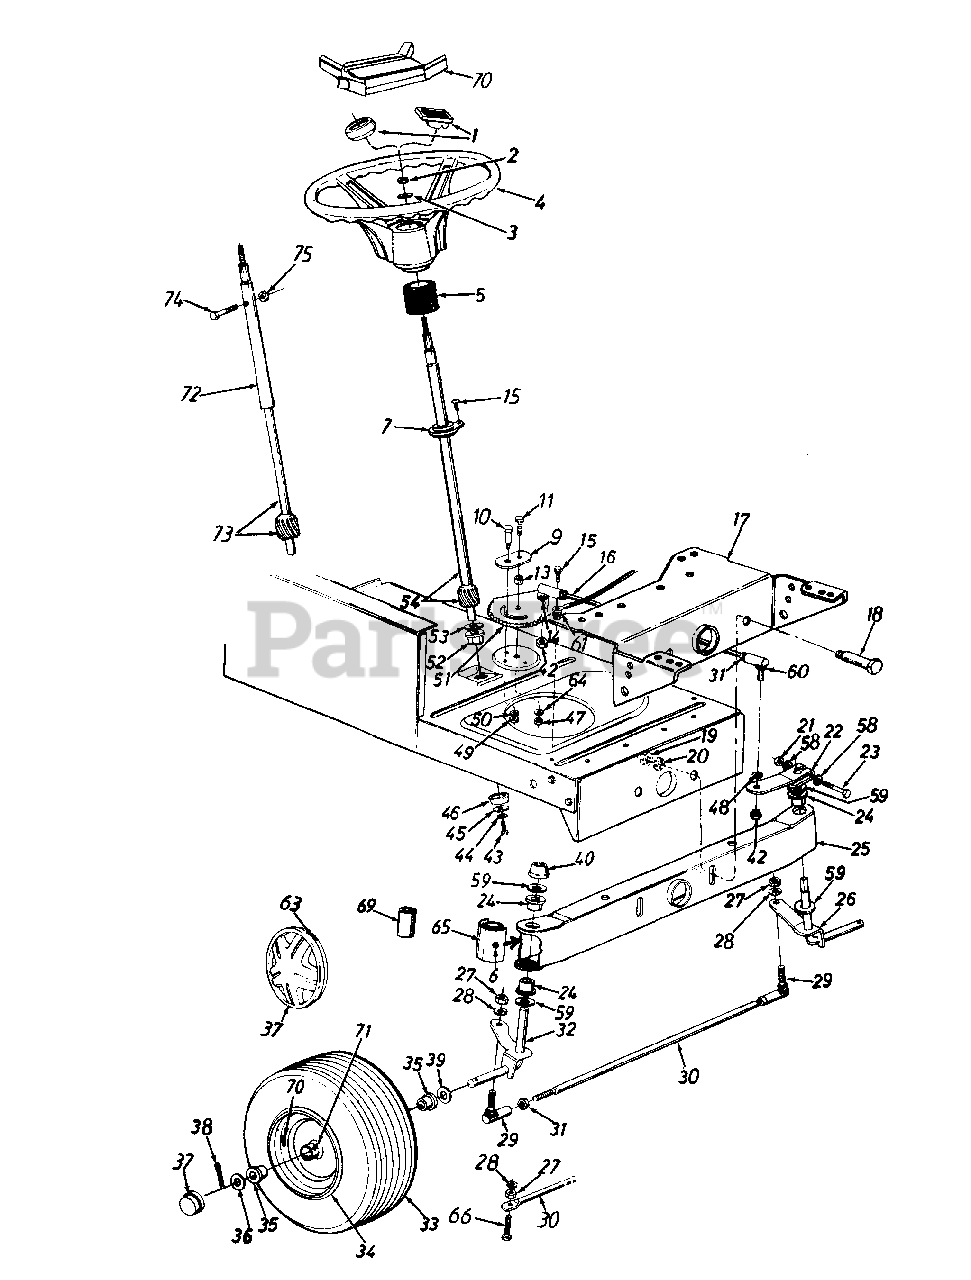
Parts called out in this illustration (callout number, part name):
1	Steering Wheel Cap
2	Hex L-Nut 5/16-24 Thd.
3	Belleville Wash. .345" I.D.
4	Steering Wheel (3 Spoke)
5	Steering Bellow - 4.5"
6	Grease Fitting
7	Flange Bearing .628" I.D. x 1.36 O.D.
9	Retainer Plate
10	Shoulder Bolt .437" Dia. x .35 Lg. 5/16-18 Thd.
11	Hex Bolt 3/8-24 x 1.0" Lg. (Gr. 5)
13	Spacer .380" I.D. x .625" O.D. x .227
14	L-Wash. 3/8" I.D. (H.D.)
15	Hex Wash. Hd. Self-Tap Scr.
16	Steering Drag Link
18	Shoulder Bolt .498" Dia. x 2.04 Lg. 3/8-16 Thd.
19	Flanged L- Nut 3/8-16 Thd.
20	L-Wash. 3/8" I.D.
21	Hex L-Nut 5/16-24 Thd.
22	Steering Arm Front Axle
23	Hex Bolt 5/16-24 x 2.00" Lg. (Gr.5)
24	Hex Flg. Brg. .632 I.D.
26	Front Axle Ass'y. - L.H.
27	Hex Nut 3/8-24 Thd.
28	L-Wash. 3/8" I.D.
29	Ball Joint 3/8-24 Thd.
30	Tie Rod (Adjustable)
31	Hex Jam Nut 3/8-24 Thd.
32	Front Axle Ass'y. - R.H.
36	Fl-Wash. .635 I.D. x 1.59" O.D.
37	Front Wheel Hub Cap
38	Cotter Pin 1/8" Dia. x 1.25"
39	Fl-Wash. .640" I.D. x 1.24" O.D.
40	Push Cap 5/8" Dia. Rod
42	Hex Jam Nut 3/8-24 Thd.
43	Hex L-Bolt 5/16-18 x .62"
44	L-Wash. 5/16" I.D.
45	Fl-Wash. .33" I.D. x 1.25" O.D.
46	Spacer (Plastic)
47	Hex Cent. L-Nut 3/8-24 Thd.
48	L-Wash. 3/8" I.D.
49	Hex Cent. L-Nut 5/16-18 Thd.
50	L-Wash. 5/16" I.D.
51	Steering Gear Segment
52	Hex Flg. Brg. .634 I.D.
53	Fl-Wash. (Hardened)
54	Steering Shaft
57	Oval Hd. Cr.-Sunk Scr. #10 x 5/8" Lg.
58	Wave-Wash. .32" I.D. x .62" O.D.
59	Fl-Wash. (Hardened)
60	Drag Link Ball Joint 3/8-24 Thd.
61	Ext. L-Wash. 5/16" I.D.
63	Spring Clip
64	Bell-Wash. .39" I.D. x 1.38" O.D.
65	Pivot Bar End Cap
66	Hex Bolt 3/8-24 x 1.5" Lg. (Gr. 5)
69	Plastic Tube 1.54" Lg.
70	Steering Wheel Insert
72	Upper Steering Shaft
73	Lower Steering Shaft
74	Hex Bolt 1/4-20 x 1.25" Lg.
75	Hex L-Nut 1/4-20 Thd.
